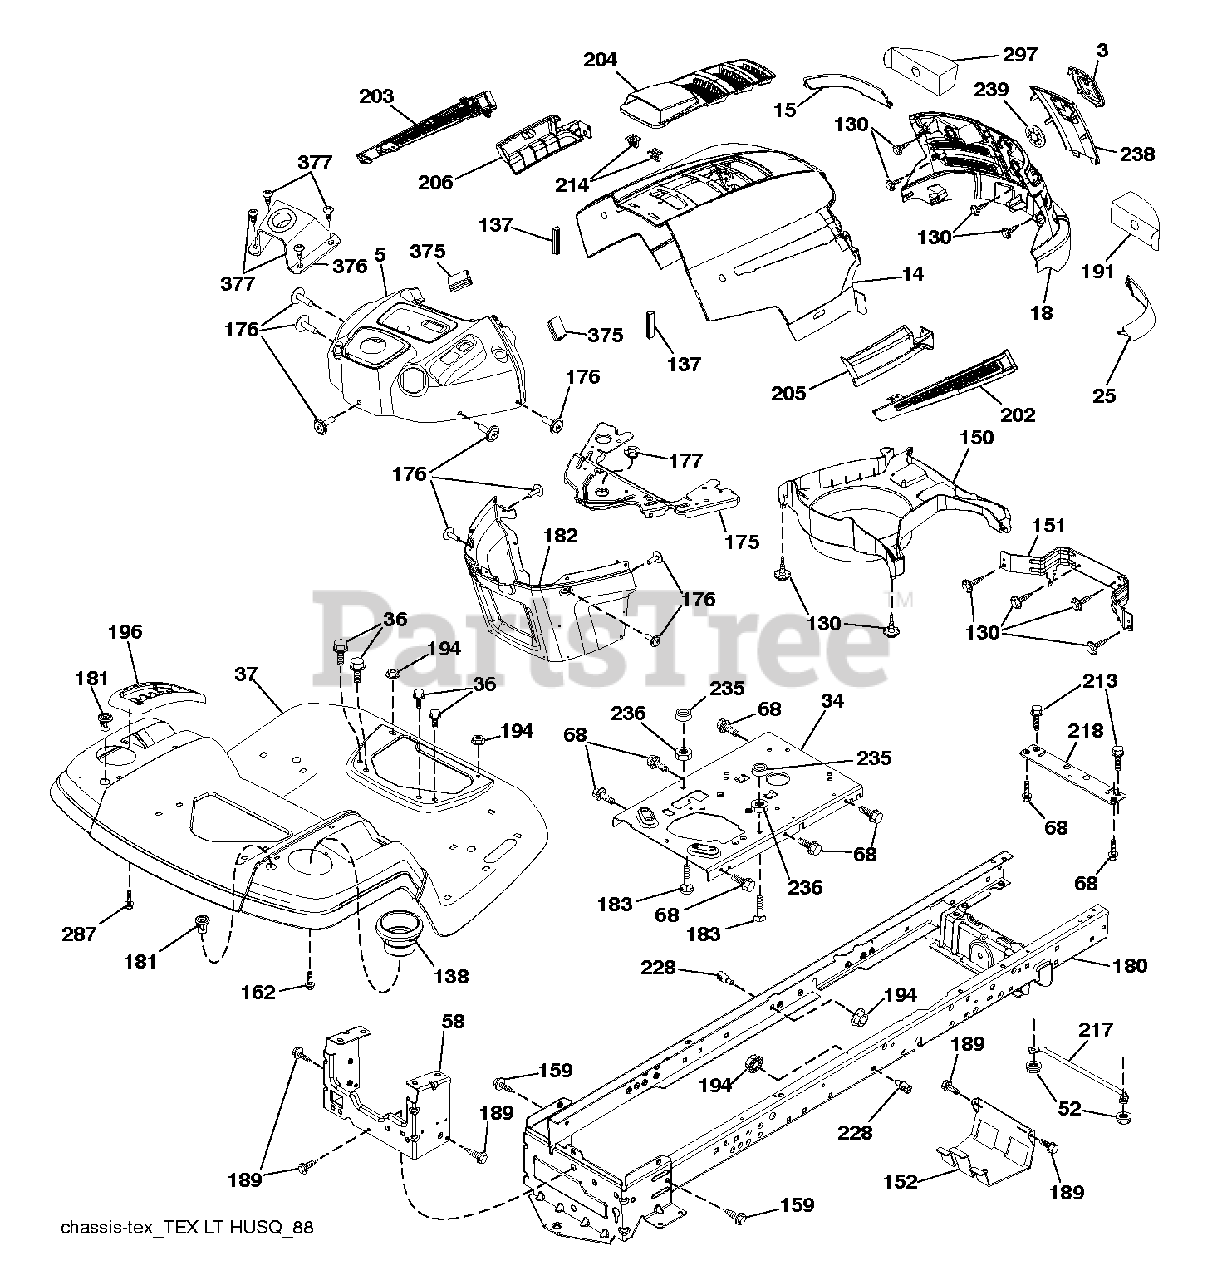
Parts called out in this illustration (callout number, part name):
3	LOGO.HUSQ.GT.LT.CROWN.H
5	DASH.UPPER.HUSQ LT CABLE.CLUTC
14	HOOD.HUSQVARNA.LT.ORANGE
15	LENS.HUSQVARNA LT.RH
18	GRILLE.SVC.HUSQVARNA.GREY
25	LENS.HUSQVARNA LT.RH
34	PLATE.ENGINE.WELDED.CHASSIS
36	SCREW 5/16"
37	FENDER.TLT.PDL.CNTRL.W/CPH.ORG
52	LOCKNUT
58	DRAWBAR UPPER 2PC SMALL FENDER
68	SCREW LT
130	SCREW.#10 X 0.750.BOS
137	BUMPER DASH
138	HOLDER.CUP.LT.GREY
151	BRACKET PIVOT
152	SHIELD.BROWNING.W/TEX
159	SCREW, 3/8-16X3/4
162	SCREW.HI-LO.CONSOLE
175	CROSSMEMBER
176	SCREW.#10-24X5/8.RN.QU
177	BUSHING STEERING
180	CHASS.WLDMNT.TL.12GA/2P.48/54
181	BUSHING.MNT.FEND.CRGO.TEX.49
182	DASH.LOWER.PREDATOR LT
183	BOLT.5/16-18X1-1/4 FULL THD
189	SCREW
191	INSERT.REFLECTIVE.RH.
194	NUT LOCK HEX FLANGE 5/16-18
196	DECKLFT.CONSOL FULL ASSM GREY
202	VENT.SIDE.HUSQVARNA.LT.RT
203	VENT.SIDE.HUSQVARNA.LT.LFT
204	SUBASM.TOP.VENT.HUSQ.LT
205	SKIRT.SIDE.HUSQVARNA.LT.RT
206	SKIRT.SIDE.HUSQVARNA.LT.LEFT
213	BOLT
214	CLIP.RETAINER.TINNER.
217	ROD.PIVOT.HOOD
218	X-PIECE.HOOD.STOP.NON/
228	STUD.FASTNER.W/ANTI-ROTATE
235	SPACER FENDER
236	NUT.CENTERLOCK.5/16-
238	TRIM.HUSQ LT.668
287	SCREW 1/4X20
297	INSERT REFLECTIVE
375	BUMPER CLIP-ON. DASH 1"
376	MOUNT.ASM.HUSLT.UPPER.STRNG
377	SCREW 10 X 1/2 ZN PL PHIL PAN
